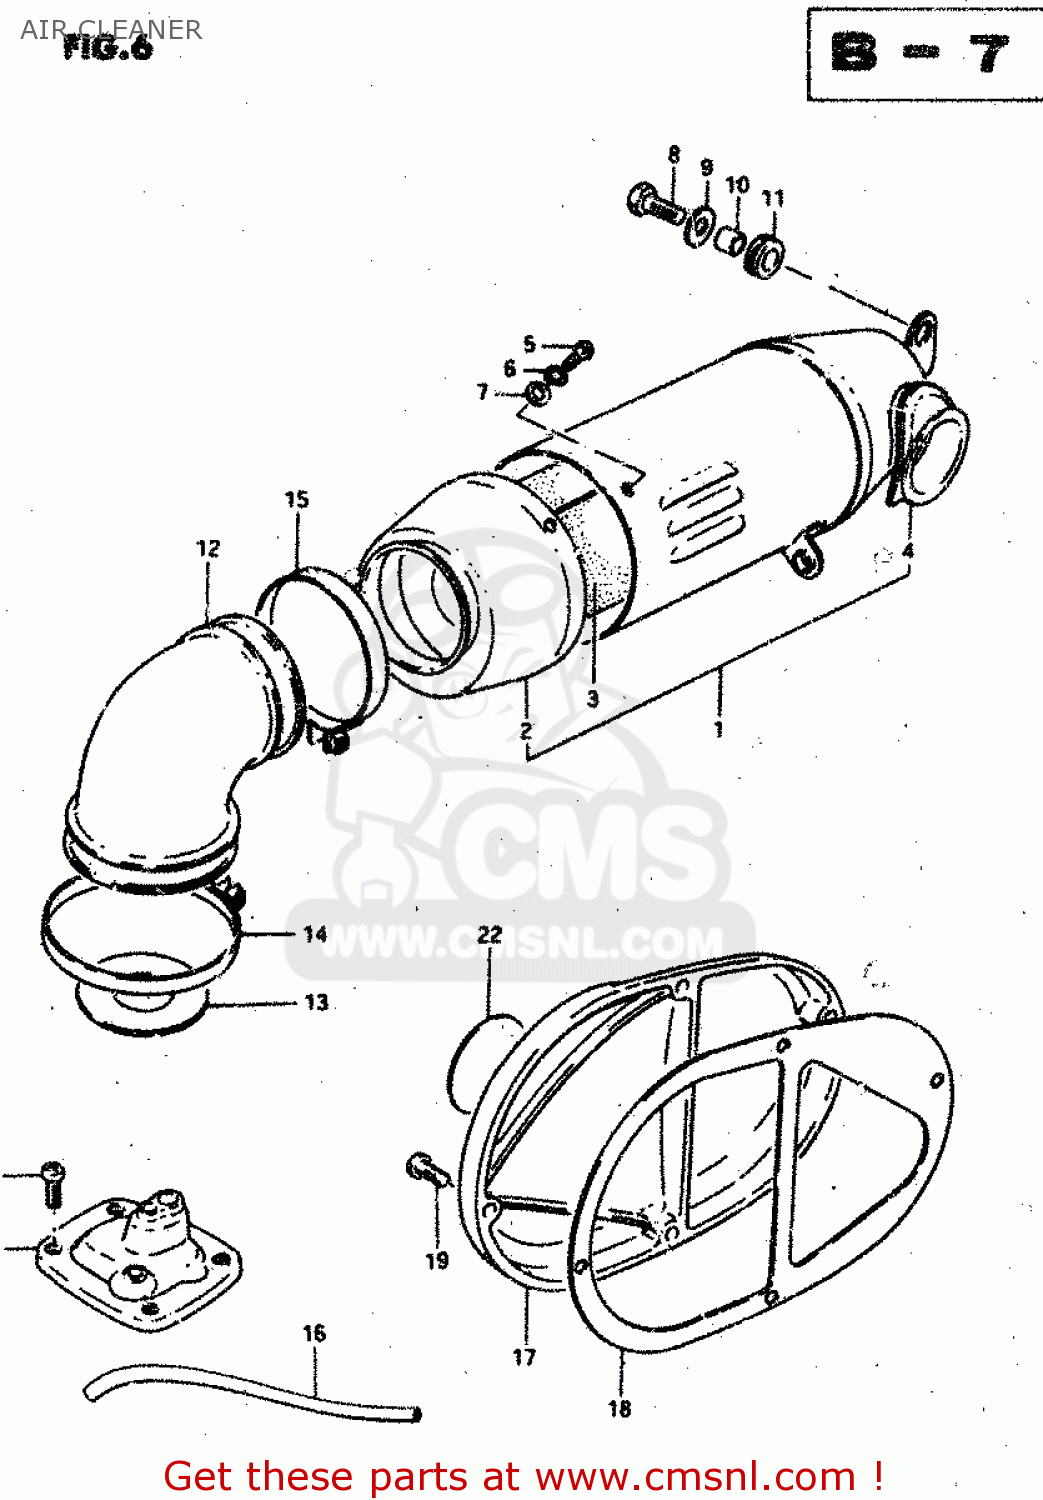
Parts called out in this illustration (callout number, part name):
1	CLEANER ASSY, AIR
2	FILTER ASSY
3	FILTER,AIR CLEANER
4	PIPE,AIR CLEANER INLET
5	SCREW
6	LOCK WASHER
7	WASHER
8	BOLT, UPPER
9	WASHER (6.5X20X1.2)
10	SPACER (7X9X7)
11	CUSHION
12	HOSE, CARBURETOR AIR INLET
13	PLATE, CARBURETOR AIR INLET
14	CLAMP
15	CLAMP
16	HOSE
17	CAP, CARBURETOR INSPECTION
18	GASKET (MCA)
19	SCREW 5X20
20	COVER,CARBURETOR TOP
21	SCREW(5X14)
22	EMBLEM,CARB INSPECTION CAP
